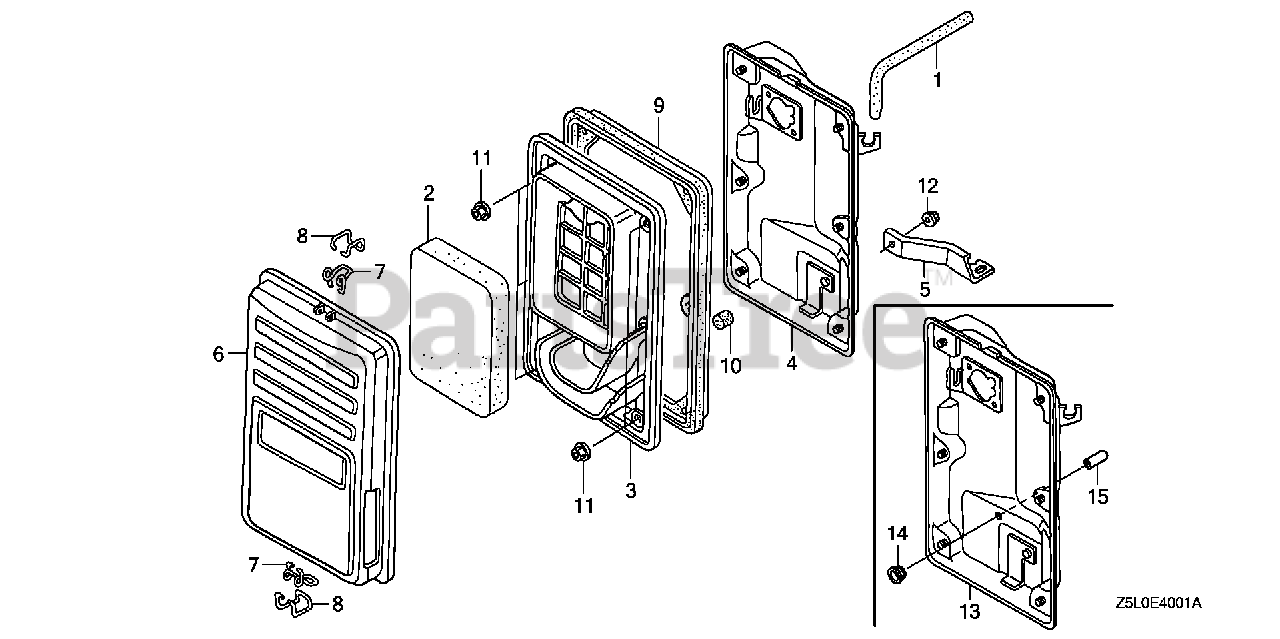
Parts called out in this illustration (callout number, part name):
1	TUBE, BREATHER
2	ELEMENT, AIR CLEANER
3	SEPARATOR, AIR CLEANER
5	STAY, AIR CLEANER
6	COVER, AIR CLEANER
7	CLIP A, AIR CLEANER WIRE
8	CLIP B, AIR CLEANER WIRE
9	SEAL, AIR CLEANER
10	FILTER, DRAIN TUBE
11	NUT, FLANGE (5MM)
12	NUT, FLANGE (6MM)
13	HOUSING, AIR CLEANER
14	GROMMET, AIR CLEANER
15	CAP, SEALING
